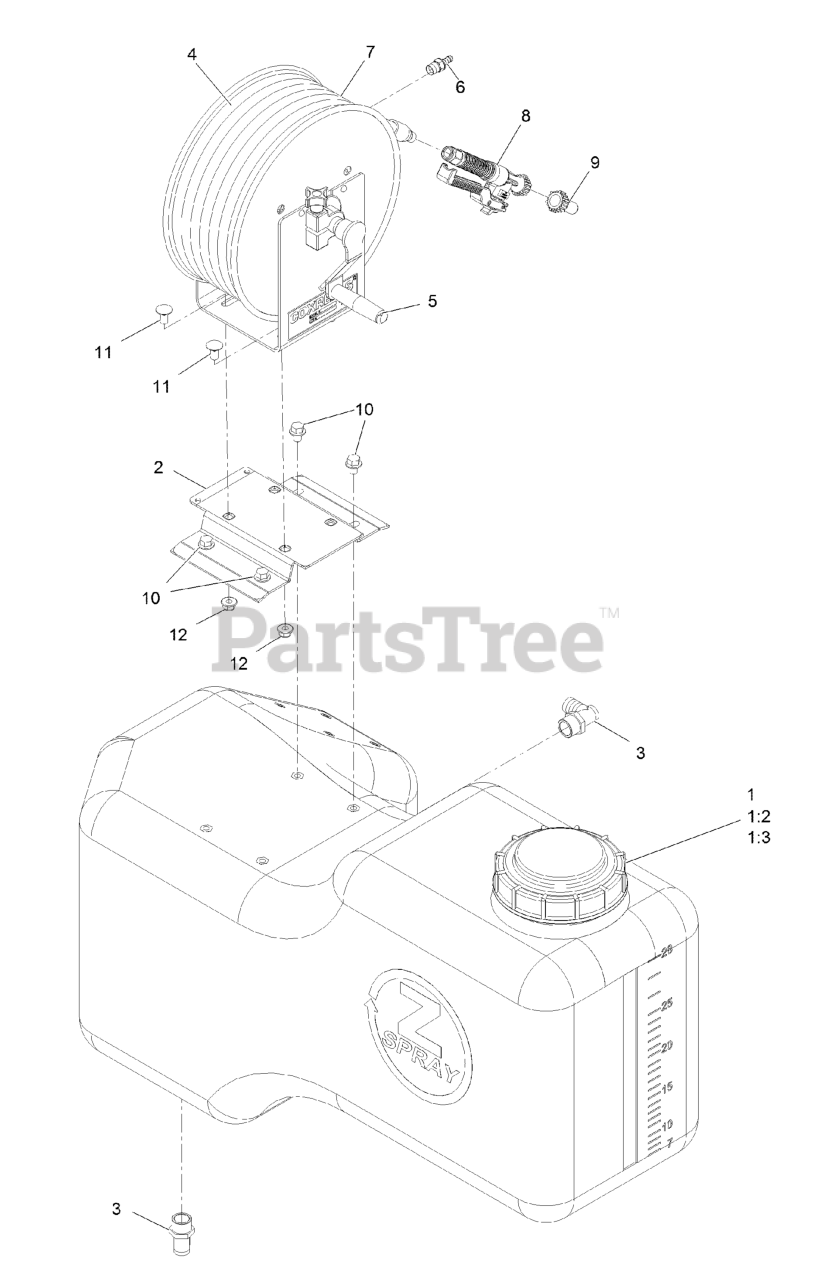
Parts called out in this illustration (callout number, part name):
1	ASM-Tank, Lt
1:2	CAP-TANK, SPRAY
1:3	FITTING-BULKHEAD
2	MOUNT-REEL, HOSE
3	FITTING-ELBOW, 90
4	REEL-HOSE
5	Crank-Reel
6	FITTING,MALE
7	HOSE-SPRAY, 75'
8	GUN-SPRAY, SPOT
9	TIP-SPRAY, #12 SPOT
10	Screw-HHF
11	SCREW-CARRIAGE
12	Nut-Hex Flange
